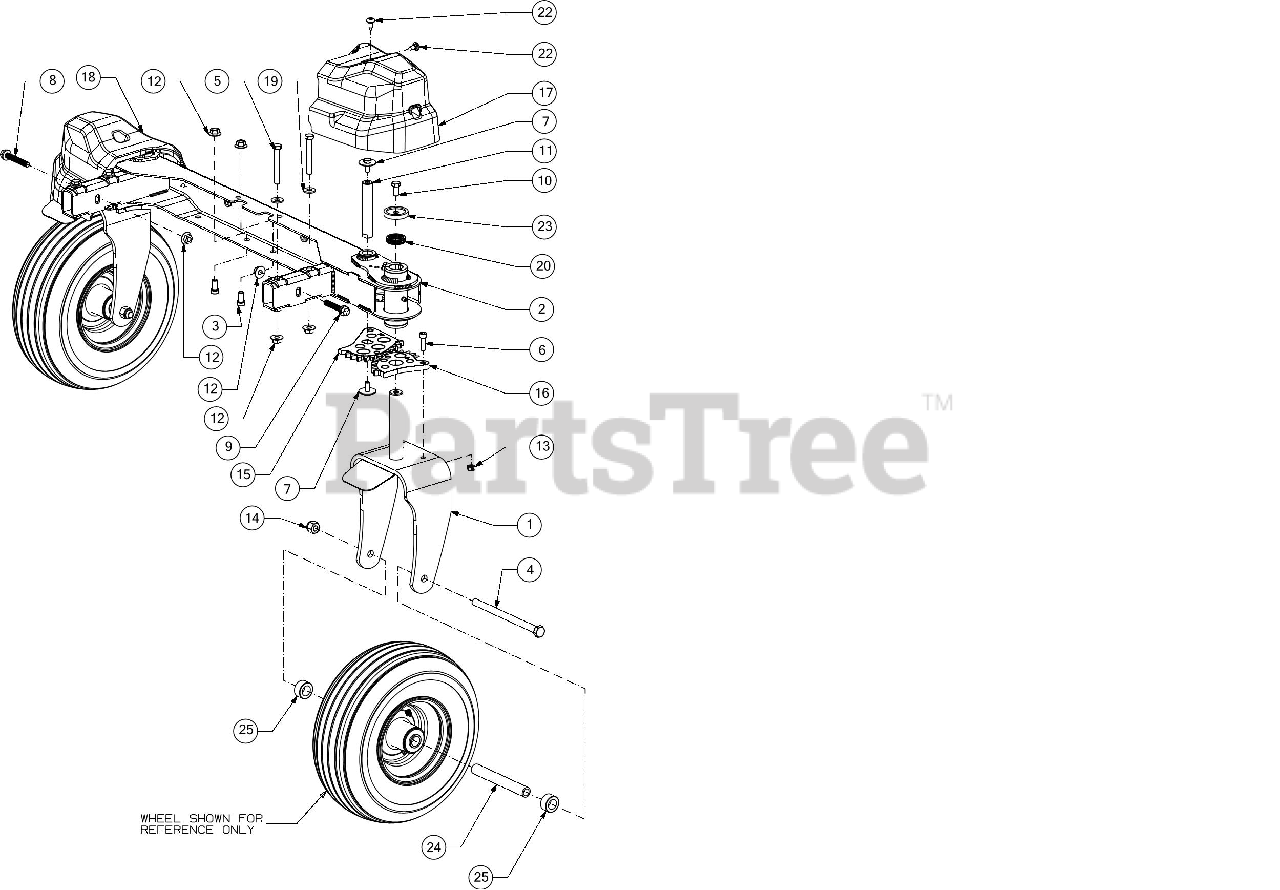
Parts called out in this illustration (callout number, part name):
1	CASTER WHEEL YOKE
2	FRONT AXLE ASSEMBLY
3	HEX SCREW 3/8-16 x .75
4	BOLT 1/2-20 x 7.25 GR5
5	SCREW 3/8-16 x 2.75 GR5
6	SCREW 5/16-18 x 1
7	SCREW 5/16-18 X.75 GR5
8	SCREW 3/8-16 x 2.25 GR5
9	SCREW 3/8-16 x 2.00 GR5
10	SCREW 3/8-16 x .75 GR 5
11	STEERING GEAR PIVOT SHAFT
12	FLANGE LOCK NUT
13	HEX NUT
14	HEX NUT CENTER
15	STEERING GEAR
16	STEERING SPUR GEAR 13T
17	AXLE COVER (RH)
18	AXLE COVER (LH)
19	FLAT WASHER .385X.870X.090
20	WAVE WASHER
22	TORX SHOULDER SCREW 1/4-20
23	SHOULDER SPACER 1.75 OD
24	CASTER SPACER
25	SPACER .76X1.23X.63
